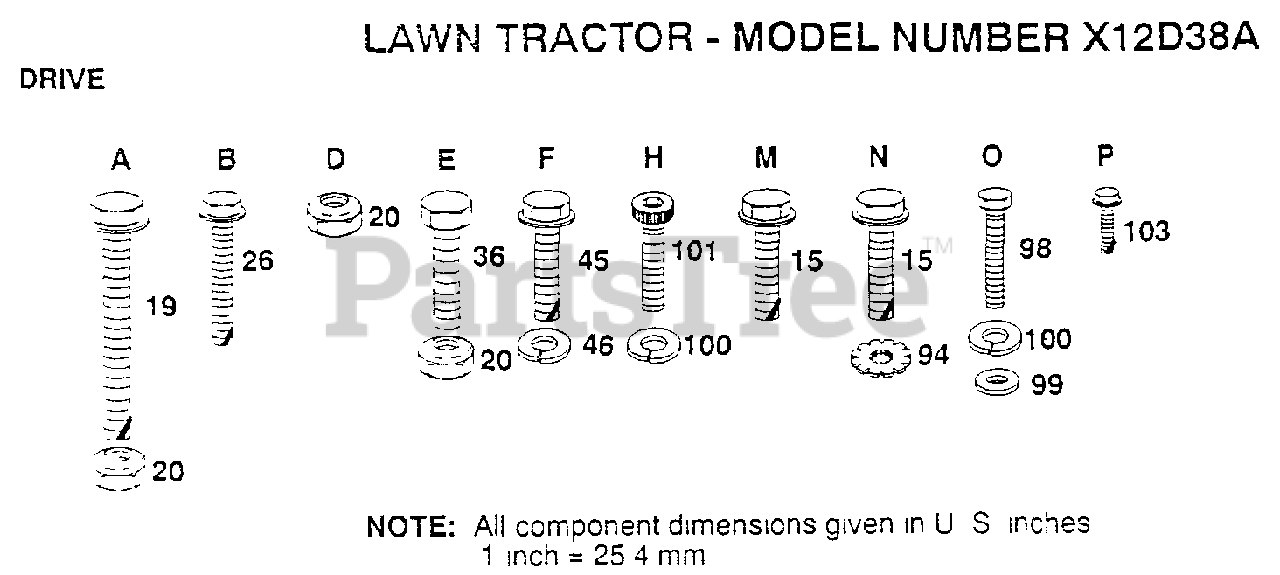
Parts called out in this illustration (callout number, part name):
15	SCREW
19	BOLT
26	SCREW
45	SCREW
46	WASHER
94	LOCKWASHER
98	BOLT
99	WASHER
100	LOCKWASHER
101	SCREW LT
